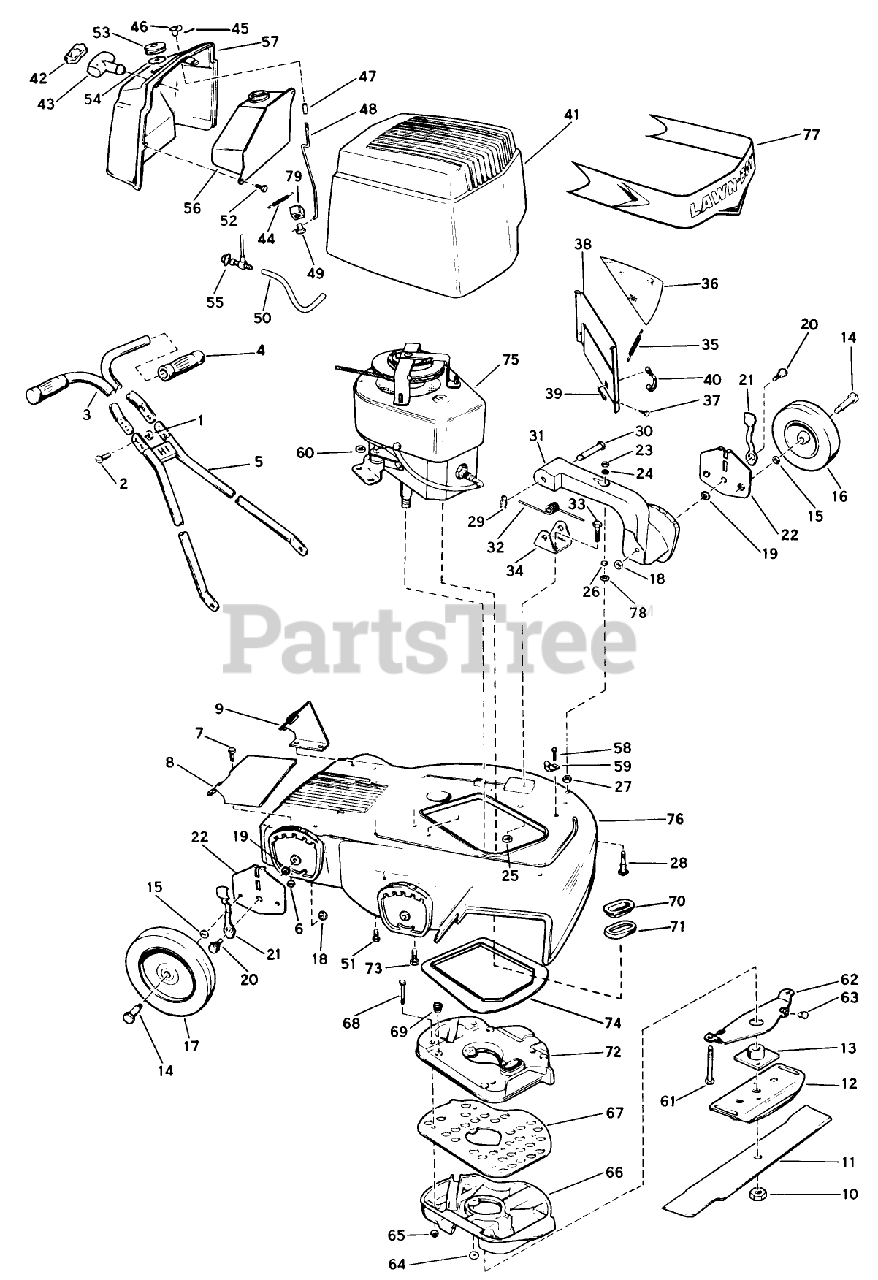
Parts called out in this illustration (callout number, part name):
1	STOP NUT
10	NUT-BLADE
13	PLATE AND COLLAR ASM
14	BOLT WHEEL
23	STOP NUT
24	Washer-Level Ride, Fiber
25	STOP NUT
26	Washer-Level Ride Arm
27	Jam Nut
28	Bolt-Level-Ride Arm
29	Hair Pin-Level Ride Arm
30	Pin-Level Ride Arm
32	Spring-Level Ride Arm
33	Screw-Level-RideArm Bracket
34	Bracket-Level Ride Arm
36	Screen-Sound Trap
37	Screw-Thread Cutting
38	Shield Sound Trap
41	Bonnet-Front
45	Cotter Pin-Choke Knob
46	KNOB, CHOKE BAR
48	Rod-Choke
49	Pivot-Choke Rod (Nylon)
52	Screw-Thread Cutting
53	Gas Cap
57	Bonnet-Rear
58	Screw-Thread Cutting
59	Latch-Bonnet
61	Screw-Engine Mtg., Long
62	Bracket-Crankshaft Limit Stop
63	Bumper-Crankshaft Limit Stop
64	Nut-Muffler to Crankcase Studs
65	LOCKNUT E
66	Muffler-Bottom
67	Gasket-Muffler
68	Bolt-Muffler
69	Spring-Muffler
72	Muffler-Top
74	Seal-Dust
76	Housing, 19"
77	Decal-LAWN-BOY
79	Retainer-Choke Rod
